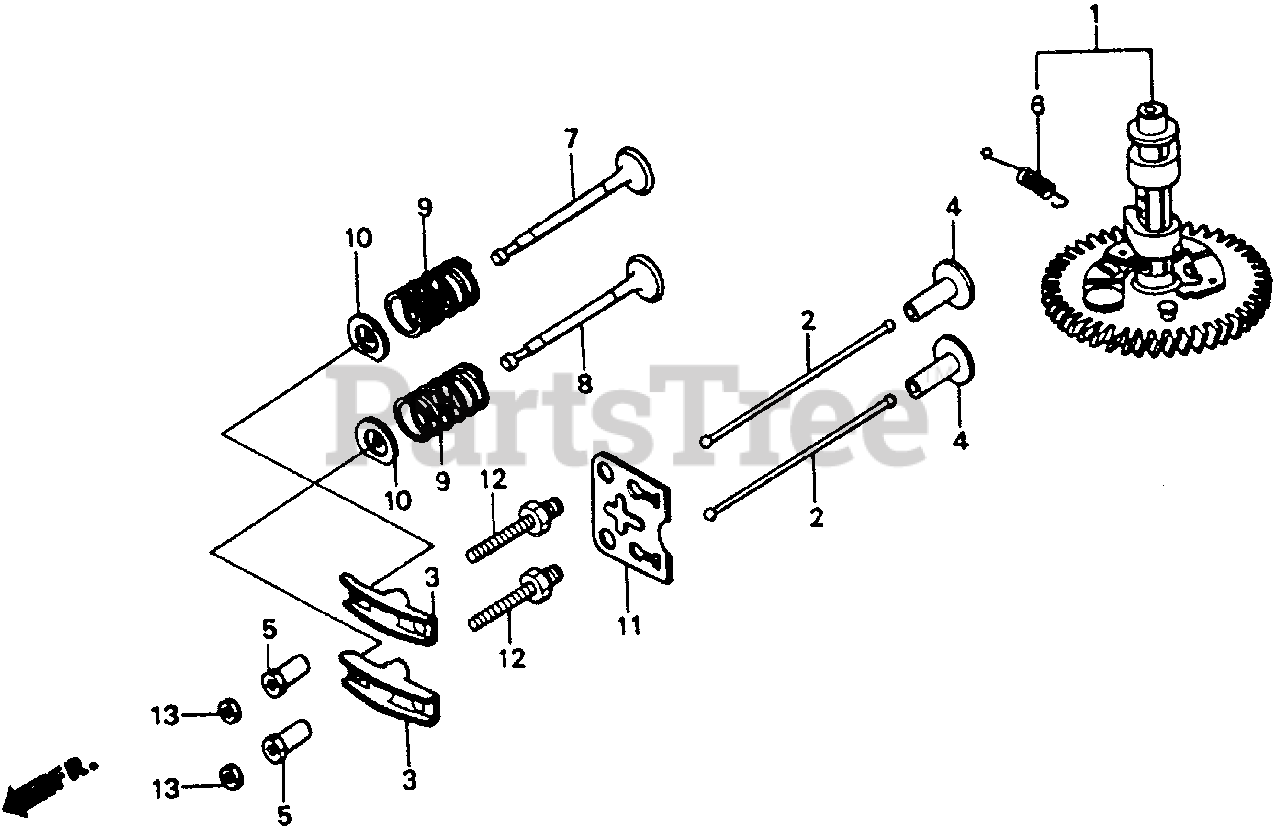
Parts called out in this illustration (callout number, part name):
1	CAMSHAFT ASSY.
2	ROD, PUSH
3	ARM, VALVE ROCKER
4	LIFTER, VALVE
5	PIVOT, ROCKER ARM
6	SPRING, WEIGHT RETURN
7	VALVE, IN.
8	VALVE, EX.
9	SPRING, VALVE
10	RETAINER, IN. VALVE SPRING
10	RETAINER, VALVE SPRING (EXHAUST SIDE)
11	PLATE, PUSH ROD GUIDE
12	BOLT, PIVOT (8MM)
13	NUT, PIVOT ADJ.
